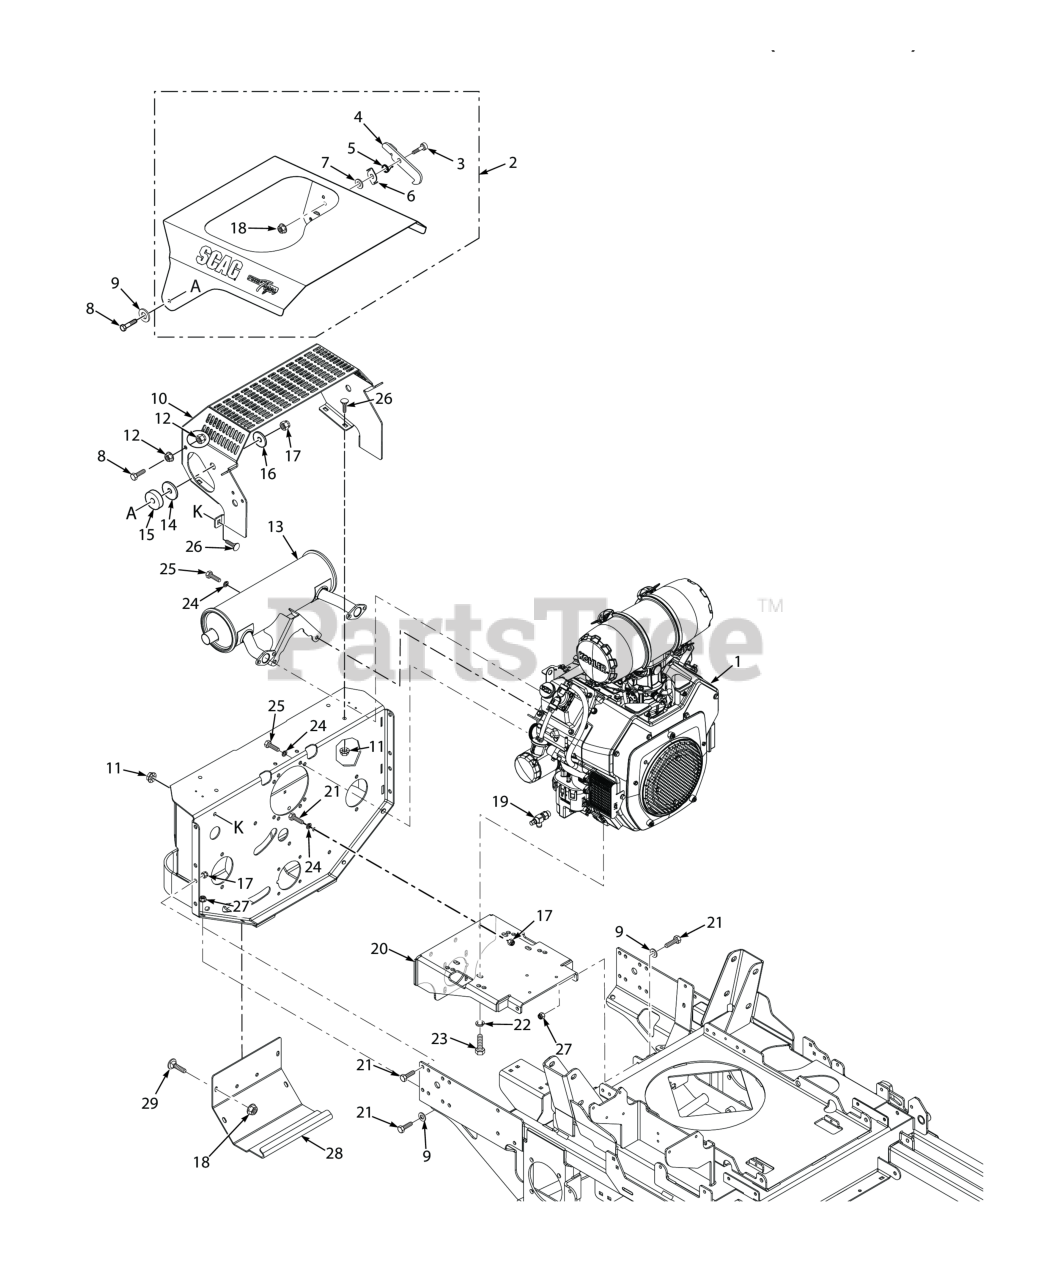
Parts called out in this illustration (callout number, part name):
3	Bolt, Shoulder 5/16-18 x 1/2"
4	Latch, Hood
5	Spring, Hood Latch
6	Lock, Hood Latch
7	Flatwasher, 3/8 (.406 x .812 x .065)
8	Bolt, Hex Head 3/8-16 x 1-3/4" (Kohler EFI)
9	Flatwasher, 3/8" Special (.391 x .938 x .105)
10	Guard, Muffler
11	Nut, Flange Head Elastic Stop 5/16-18
12	NUT, 3/8-16 SERRATED FLANGE HEX HEAD
14	Disc, Anti-Friction
15	Spacer, Hood
16	Flatwasher, 3/8-.406 x 1-1-1/2 x 7 Gauge
17	HEX NUT, ELASTIC STOP LOCK, 3/8-16
18	Nut, Serrated Flange 5/16-18 (Right Front Engine Mounting, Briggs and Kohler Only)
20	Plate Weldment, Engine Mounting
21	Bolt, Hex Head, 3/8-16 x 1 Gr. 5
22	Lockwasher, 3/8" Spring, Kawasaki FX / FT & FT-EFI / B&S 32BV
23	Nut, Serrated Flange 5/16-18 (Right Front Engine Mounting, Briggs and Kohler Only)
24	Lockwasher, 3/8" Spring, Kawasaki FX / FT & FT-EFI / B&S 32BV
25	Bolt, Hex Head, 3/8-16 x 1 Gr. 5
26	Bolt, 5/16-18 x .75 RHSN Carriage
27	Nut, Flange Elastic Stop Nut, 3/8-16
28	Cover, Rear
29	Bolt, 5/16-18 x .75 RHSN Carriage
